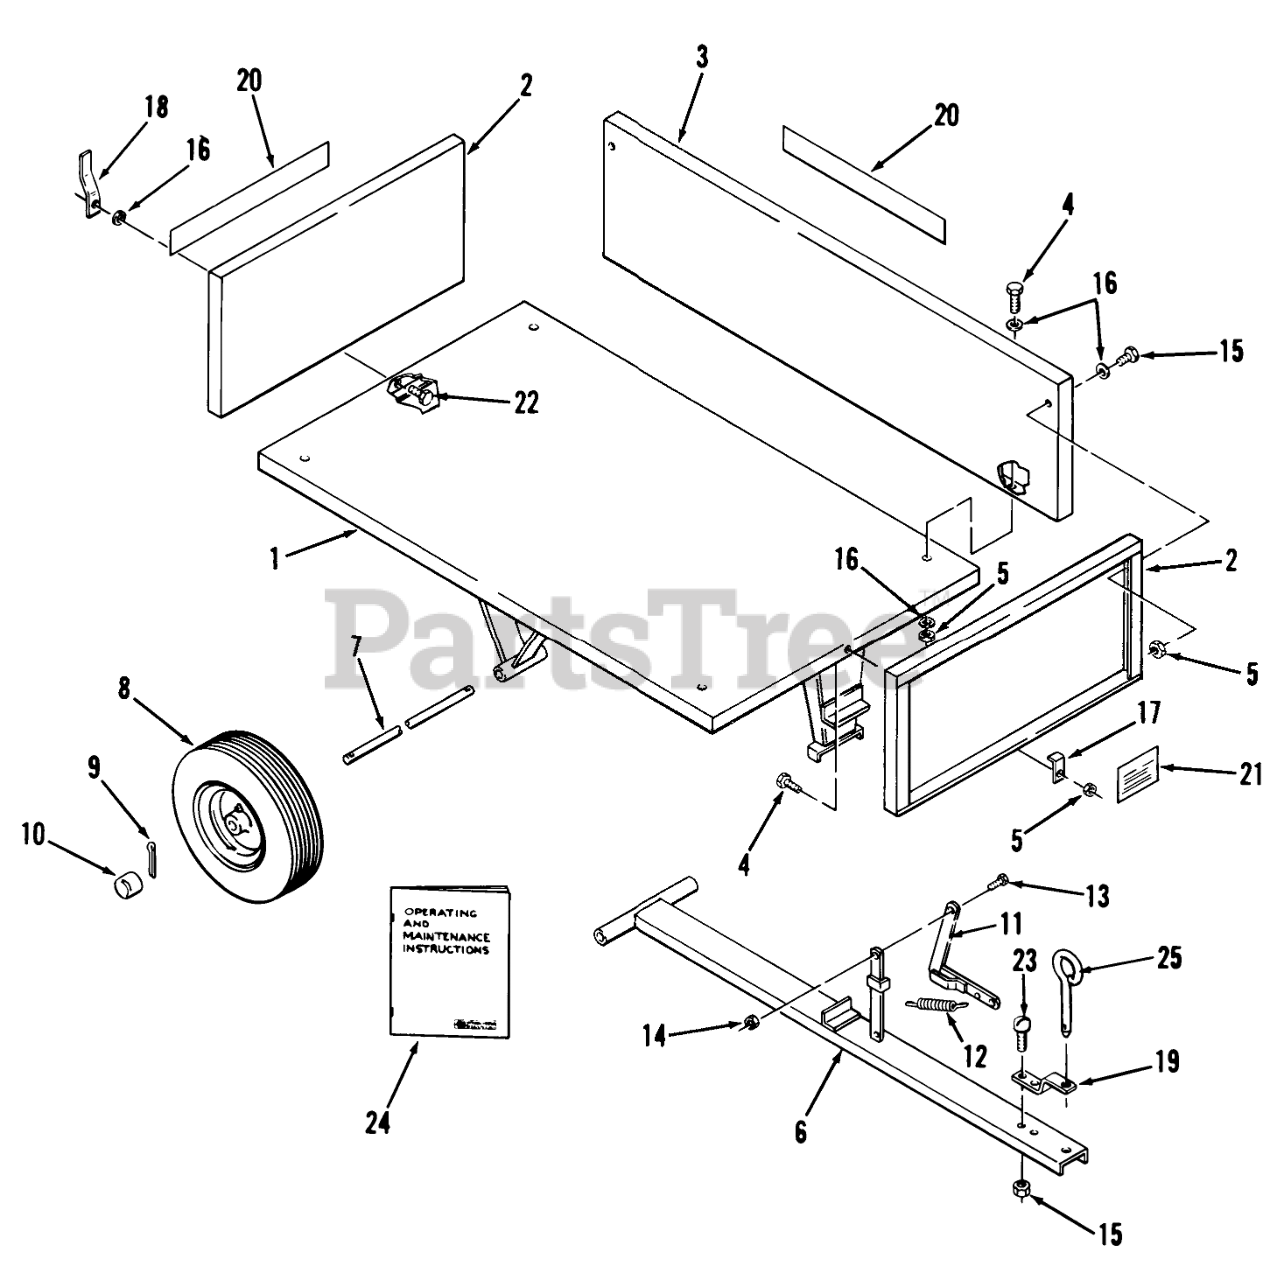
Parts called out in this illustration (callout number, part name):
1	Bed Assembly
2	Front and Rear Gate
3	Side Gate
4	BOLT
5	NUT
6	Drawbar Assembly
8	Wheel Assembly (6.50 x 8-16)
9	Cotter Pin
10	HUB CAP
11	Latch Assembly
12	SPRING
13	Bolt
14	Nut
15	Bolt
16	Washer
17	Latch-Front Gate
18	Latch-Rear Gate
19	CLEVIS-BAR
20	Decal
21	Weight Limit Decal
22	Bolt
23	Truss Hd. Bolt 3/8-16 x 3/4
24	Operating and Maintenance Instructions
25	PIN-TOOL
